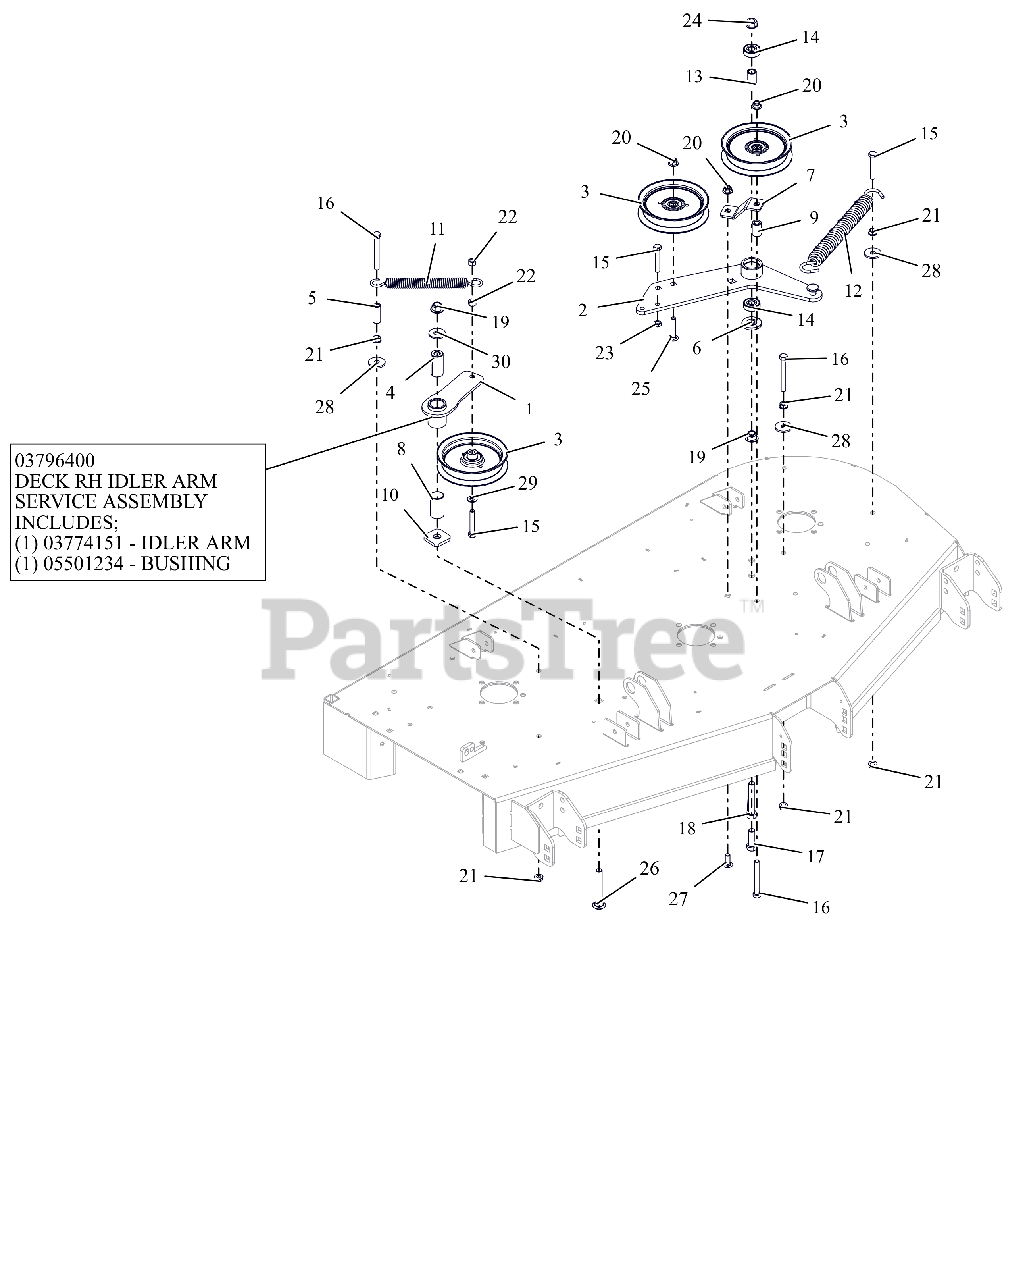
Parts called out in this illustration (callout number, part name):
1	WMT, IDLER ARM - BLACK
1	ASM, IDLER ARM (DECK)
2	DECK PTO IDLER ARM WLDMT - BLK
3	IDLER, FLAT 5.00"
4	BSHG, SPCR .502X.997X2.03 PM
5	SPACER, .375IDX.625ODX1.66 PM
6	SPACER, IDLER ARM
7	PTO FIXED IDLER MTG BRKT-ORG
8	BSHG, 1.00X1.125X1.937
9	BUSHING, SLV .380X.750X1.190
10	WSHR-FLT .640X1.75X.250
11	SPRING, EXTENSION
12	SPRING, EXTENSION
13	SPACER .510 X .75 X 1.1485
14	BRG-BALL .500X1.38X.437
15	BLT,HEX .38-16X2.25 G5 ZCC
16	BLT, HEX .38-16X3.25 G5 ZCC
17	BLT,HEX .50-13X1.50 G5 ZCC
18	BLT, HEX .50-13X3.00 G5 ZCC
19	NUT,NYL-FLG .50-13 GF ZCC
20	NUT,NYL-FLG .38-16 GF ZCC
21	NUT, SPNLK-FLG .38-16 G5 ZCC
22	NUT-LK-CTR .38-16 ZC120
23	NUT-JAM .375-16 G2 ZCC
24	NUT-LK-CTR-FLG .500-13 GG ZCC
25	BLT,RHSSN.375-16X2.00 G5 ZCC
26	BLT, RHSN .50-13X3.50 G5 ZCC
27	BLT,RHSSN .38-16X1.00 G5 ZCC
28	WSHR,FLT .406X1.375X.135 ZCC
29	WSHR,FLT .406X.812X.065 ZCC
30	WSHR,FLT .563X1.375X.109 ZCC
